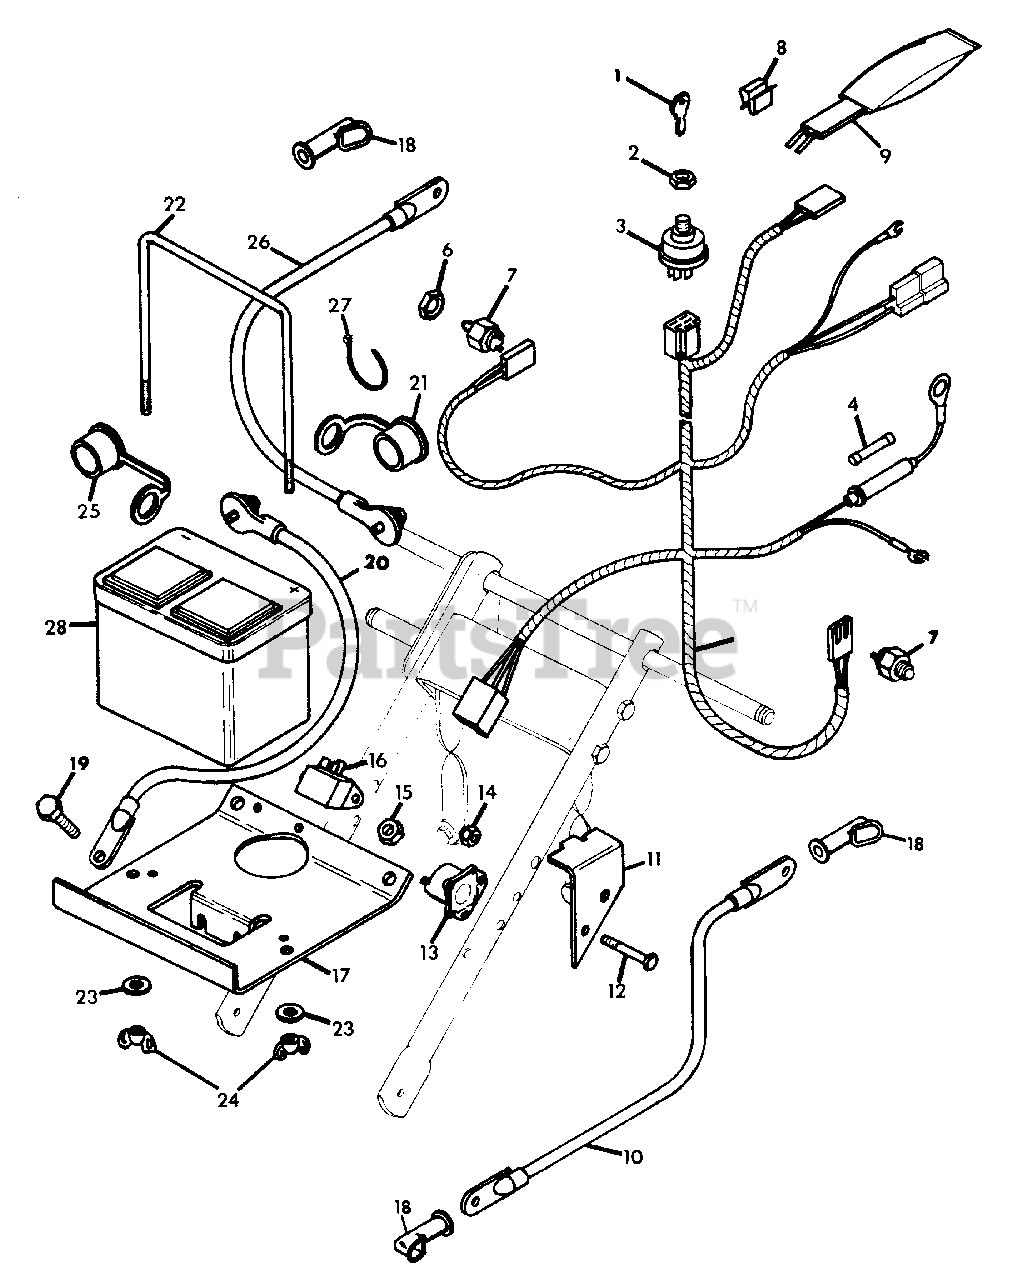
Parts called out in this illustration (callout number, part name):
1	KEY, IGNITION
2	NUT, JAM 9/16-24
3	SWITCH, IGNITION
4	FUSE, 30 AMP
5	HARNESS, WIRING
6	NUT, STAMPED
7	SWITCH, INTERLOCK
8	CLIP, WIRE
9	SWITCH, SEAT
10	CABLE
11	BRACKET, PTO
12	BOLT, HEX 1/4-20X2.00
13	SWITCH, MAG
14	NUT, LOCK 1/4-20
15	NUT, LOCK 3/8-16
16	REGULATOR, RECTIFIER
17	BOX, BATTERY
18	BOOT, BATTERY CABLE
19	BOLT, HEX 3/8-16X2.25
20	CABLE, NEGATIVE BATTERY
21	COVER, BATTERY POS.
22	ROD, BATTERY
23	WASHER, FLAT .281X.625X.065
24	NUT, WING 1/4-20
25	COVER, BATTERY NEG.
26	CABLE, POSITIVE BATTERY
27	TIE, CABLE
28	BATTERY, DELCO MAINTENANCE-FREE #101 -REPLACEMENT BATTERY #83-50
